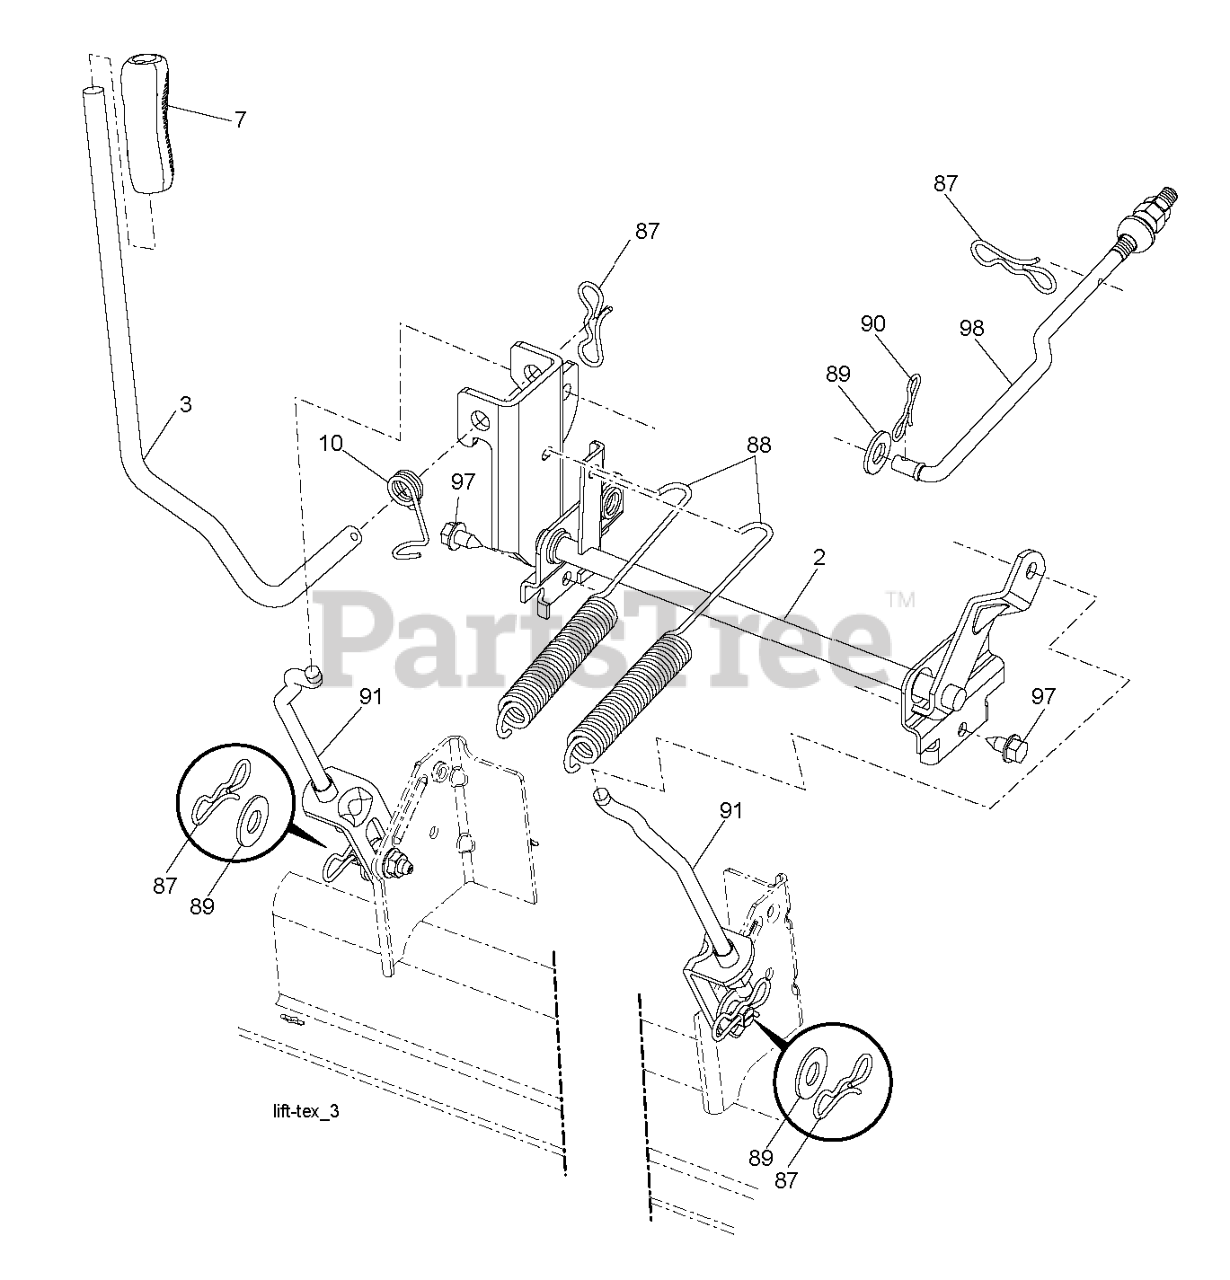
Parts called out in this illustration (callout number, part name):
2	SHAFT.ASM.LIFT.CROSS.H
3	LEVER.LIFT.HANDLE.GT
7	GRIP.HANDLE.LIFT.PVC.BLACK
10	SPRING.TORSION.LIFT.HANDLE
87	PIN.COTTER.7/16.BOW TI.
88	SPRING.LIFT.ASSIST.GT2
90	PIN.COTTER.5/16.BOW TI
91	LINK.ASM.LIFT.54"TG
97	SCREW, 3/8-16X3/4
98	LINK.ASM.SUSP.FRONT.MWR.10.5
